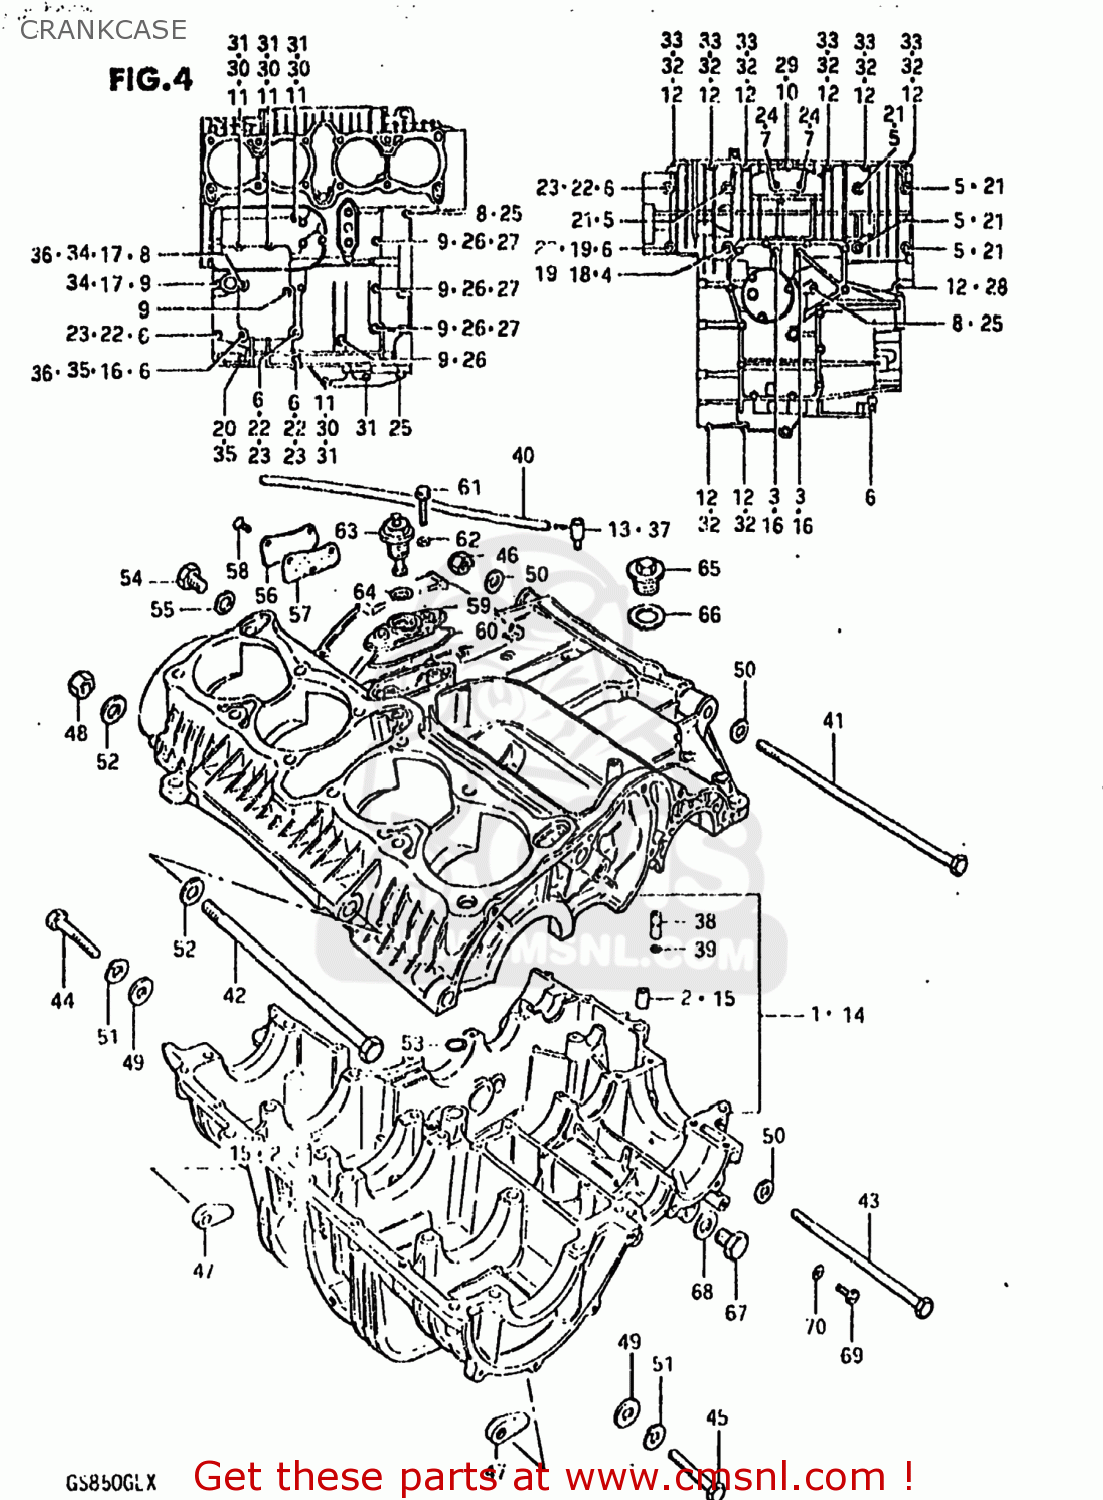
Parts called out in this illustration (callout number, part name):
1	CRANKCASE SET
2	PIN
3	BOLT
4	BOLT
5	BOLT 8X90
6	BOLT 8X65
7	BOLT
8	BOLT (6X90)
9	BOLT (6X75)
10	BOLT ,6X50
11	BOLT,UNDER
12	BOLT 6X35
13	BPLUG,BEVEL GEAR BREATHER
14	CRANKCASE SET
15	PIN
16	BOLT
17	BOLT
18	BOLT
19	BOLT
20	BOLT
21	BOLT 8X90
22	BOLT 8X65
23	BOLT 8X65
24	BOLT
25	BOLT (6X90)
26	BOLT (6X75)
27	BOLT (6X75)
28	BOLT
29	BOLT ,6X50
30	BOLT,UNDER
31	BOLT,UNDER
32	BOLT 6X35
33	BOLT 6X35
34	NUT
35	NUT
36	GASKET 8.2X14X1 (NAS)
37	BPLUG,BEVEL GEAR BREATHER
38	UNION
39	O RING(D:1.05,ID:3.1)
40	HOSE
41	BOLT 10X270
42	SHAFT,REAR SWING ARM
43	BOLT(10X165)
44	BOLT 10X60
45	BOLT (10X50)
46	NUT
47	NUT
48	NUT 12MM
49	WASHER(10.5X20X3.2)
50	WASHER
51	LOCK WASHER
52	WASHER
53	O RING(D:3.2,ID:12.9)
54	PLUG (14X12)
55	GASKET(14X19.2X2) (NAS)
56	CAP,OIL GALLERY
57	GASKET,OIL GALLERY (MCA)
58	SCREW
59	HOUSING,OIL PRESSURE SWITCH
60	O RING,PRESSURE SWITCH HOUSING
61	BOLT
62	GASKET (NAS)
63	SWITCH ASSEMBLY
64	O RING(D:1.9,ID:18.8)
65	PLUG
66	GASKET
67	PLUG
68	GASKET(14X19.2X2) (NAS)
69	SCREW(6X10)
70	GASKET (NAS)
